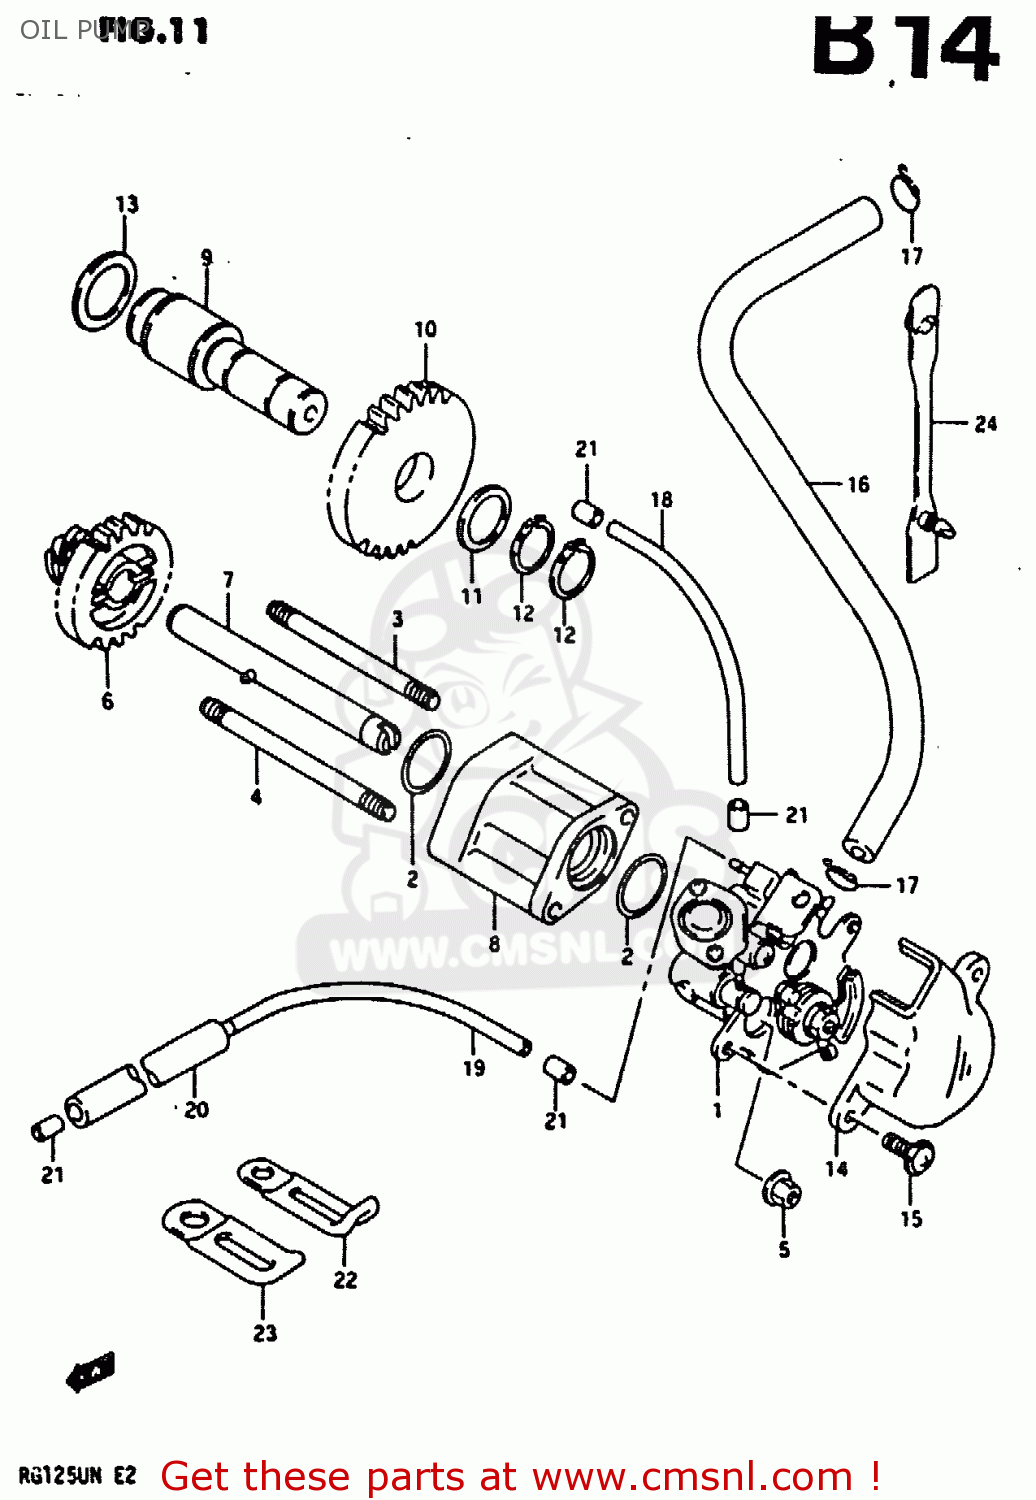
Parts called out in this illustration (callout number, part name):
1	PUMP ASSY, OIL
2	O RING(D:1.5,ID:19.5)
3	BOLT,STUD
4	BOLT,STUD
5	NUT
6	GEAR,OIL PUMP DRIVE
7	SHAFT,OIL PUMP GEAR
8	SPACER,OIL PUMP
9	SHAFT, OIL PUMP IDLE GEAR
10	GEAR, OIL PUMP IDLE (NT:29)
11	WASHER
12	CIRCLIP,17MM
13	WASHER,THRUST
14	COVER,OIL PUMP
15	SCREW
16	HOSE (4.5*8.5*300)
17	CLIP
18	HOSE (2X5X300)
19	HOSE (2X5X300)
20	HOSE
21	CLIP
22	CLAMP
23	CLAMP
24	CLAMP
